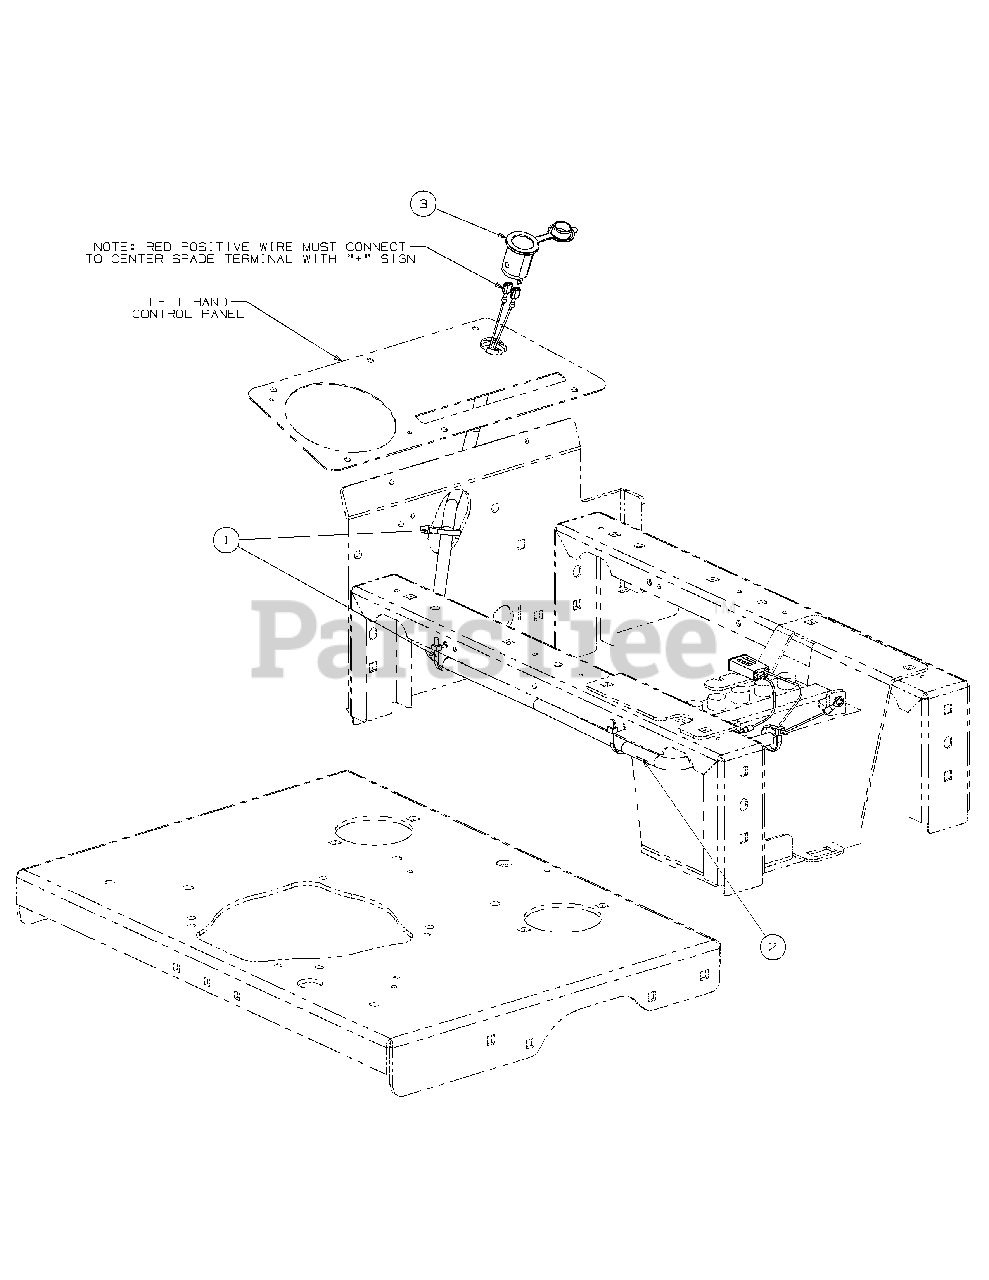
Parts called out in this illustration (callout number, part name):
1	Cable Tie
2	Wire Harness Assembly
3	12V Power Recepticle
